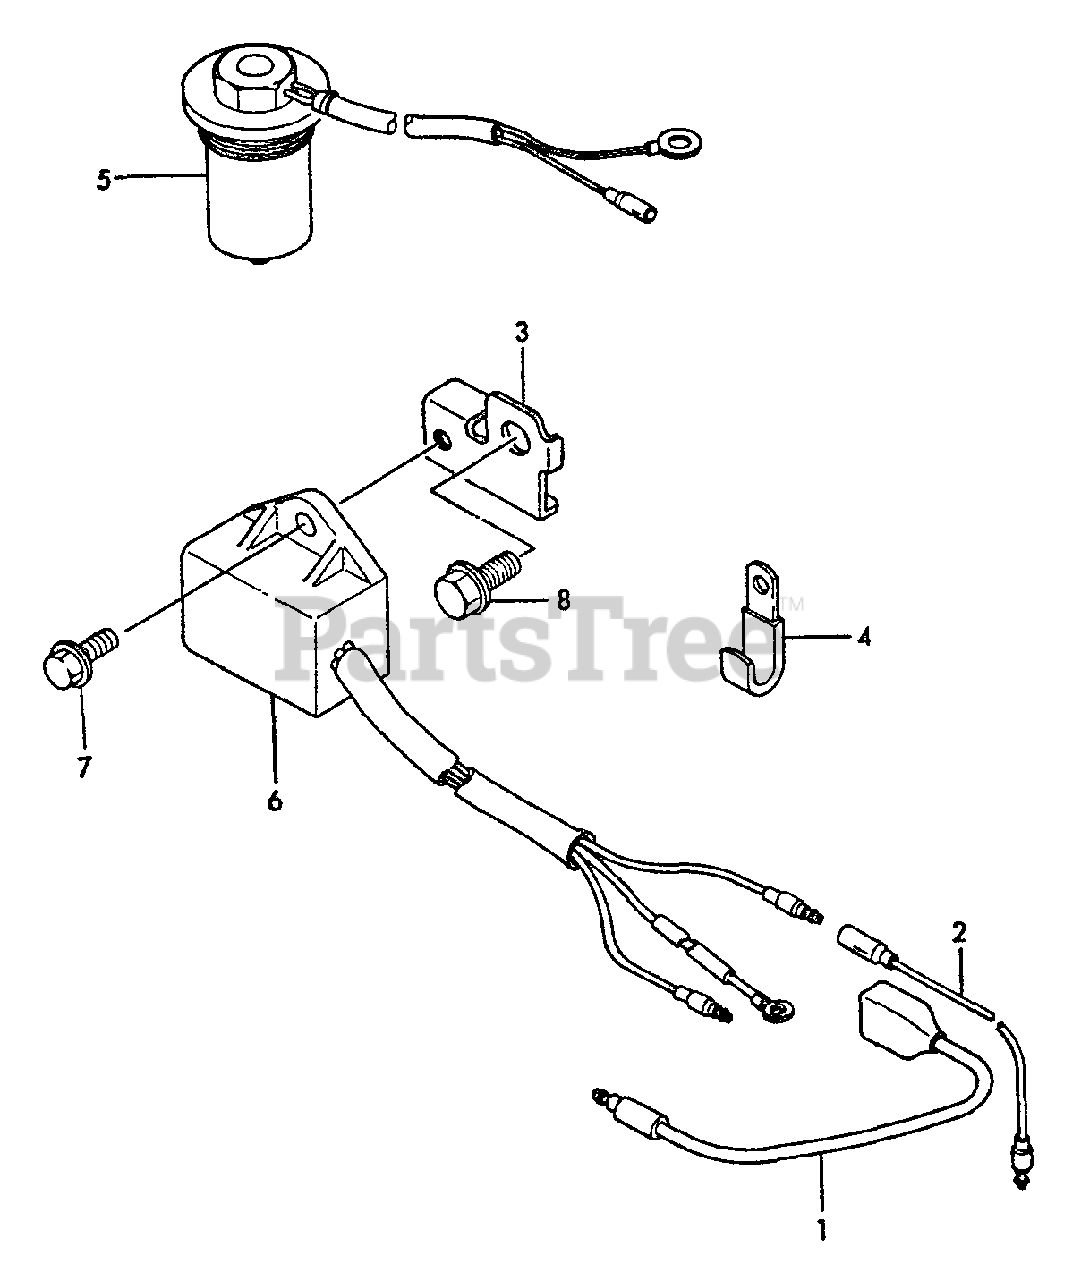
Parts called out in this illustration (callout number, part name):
1	WIRE
2	WIRE
3	STAY, SENSOR UNIT
4	CLAMP
5	SENSOR, OIL LEVEL
6	SENSOR UNIT
7	BOLT - 6×12 -- PLATED
8	BOLT - 8×14 -- PLATED
